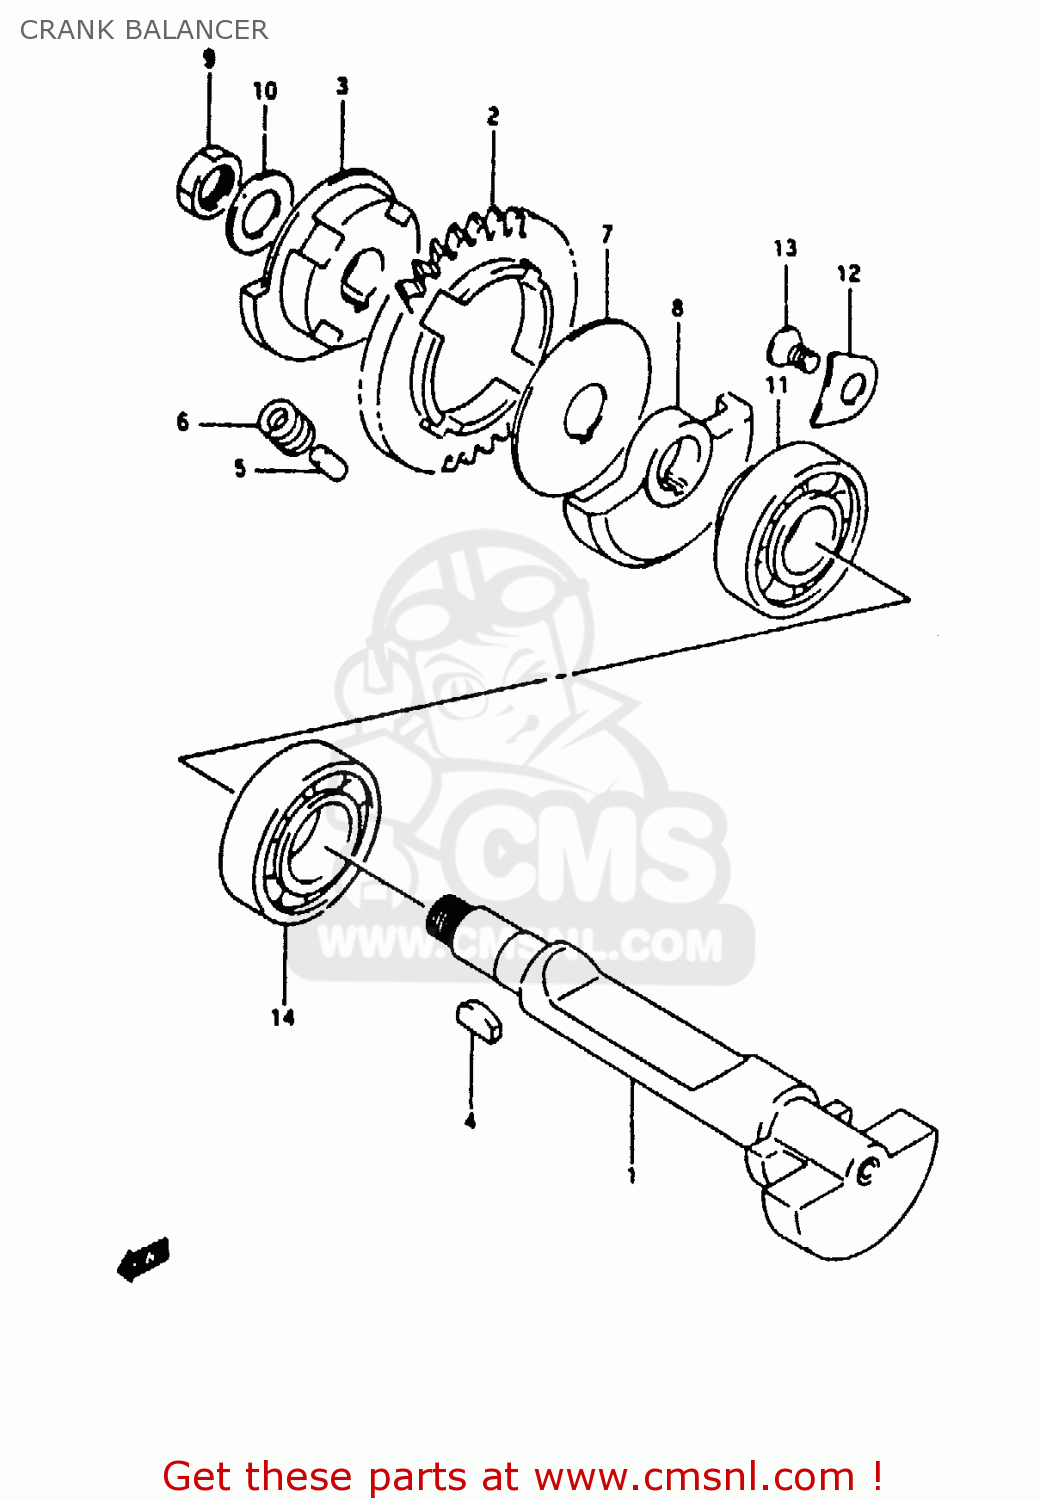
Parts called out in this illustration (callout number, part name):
1	SHAFT,CRANK BALANCER
2	GEAR, BALANCER DRIVEN
3	RACE, DRIVEN GEAR INNER
4	KEY 4MM
5	PIN(5X8.8)
6	SPRING
7	WASHER
8	WEIGHT, CRANK BALANCER RH
9	NUT
10	WASHER
11	BEARING(15X42X13)
12	RETAINER,BEARING
13	SCREW(6X12)
14	BEARING(20X42X12)
